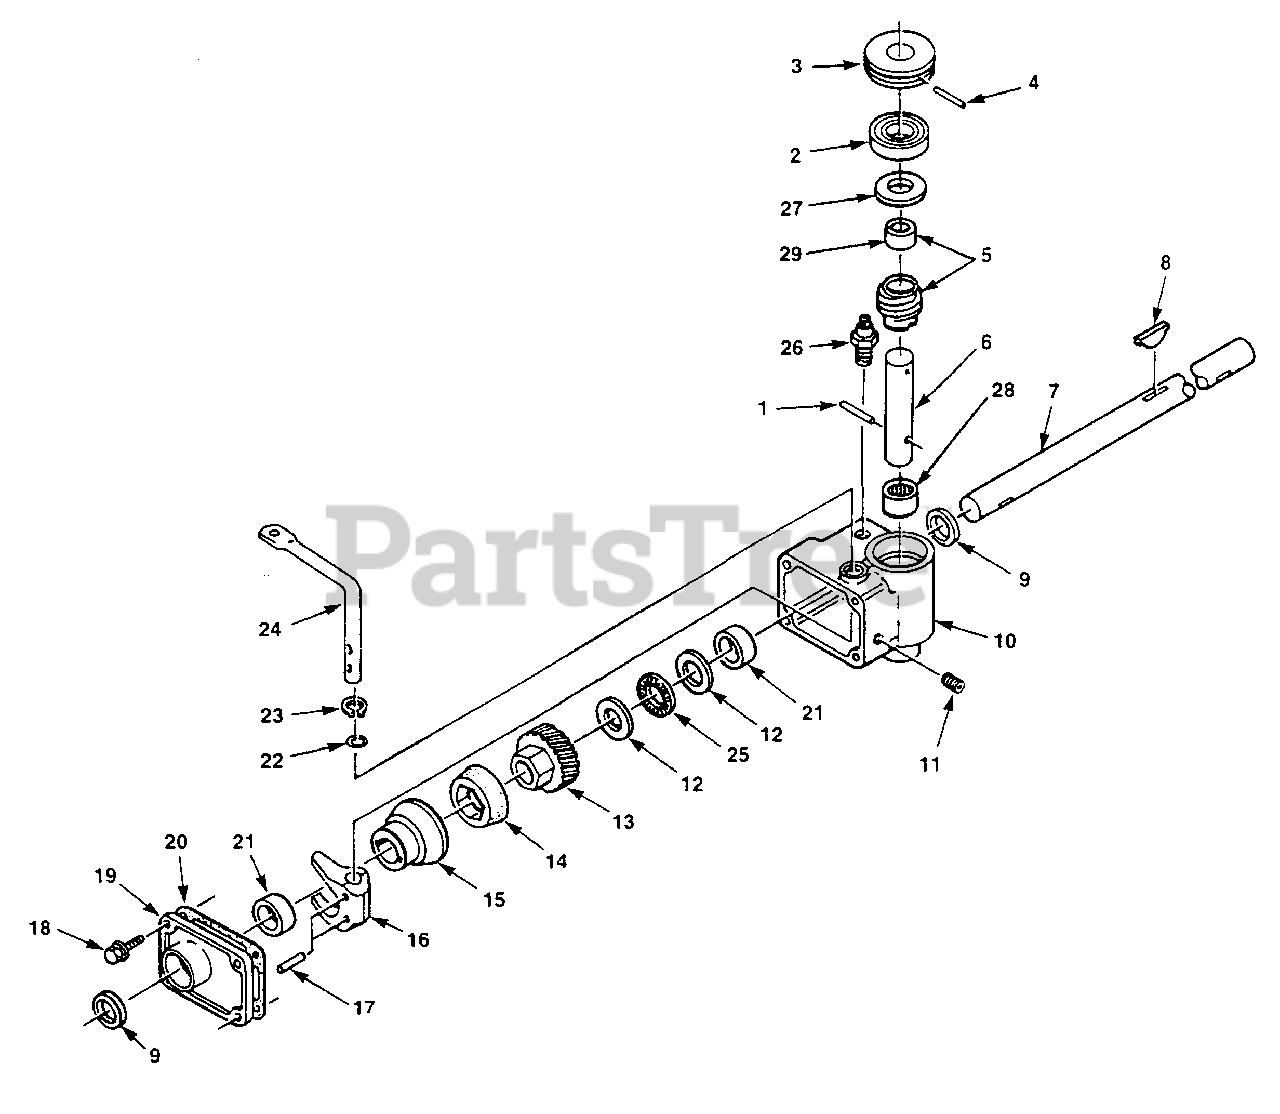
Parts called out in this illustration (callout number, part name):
1	PIN- Roll 3/16 x 7/8"
2	BEARING- Ball
3	PULLEY- Gearbox
4	PIN- Roll 3/32 x 1 1/4"
5	WORM & SPACER
6	SHAFT- Worm
7	SHAFT- Drive
8	KEY- 1/2 x 1/8"
10	GEAR REDUCER HOUSING ASSY.
11	PLUG- Pipe
12	RACE- Thrust
13	GEAR- Helical
14	CONE- Friction
15	DRUM- Clutch
16	FORK- Shift
17	PIN- Groove 5/32 x 3/4"
18	SCREW- Sems hd. 1/4-20 x 7/8"
19	COVER- Gearbox
20	GASKET- Gear box
21	BUSHING- Sleeve
24	LEVER- Shift
25	BEARING- Thrust
28	BEARING- Needle
29	SPACER- Worm gear
